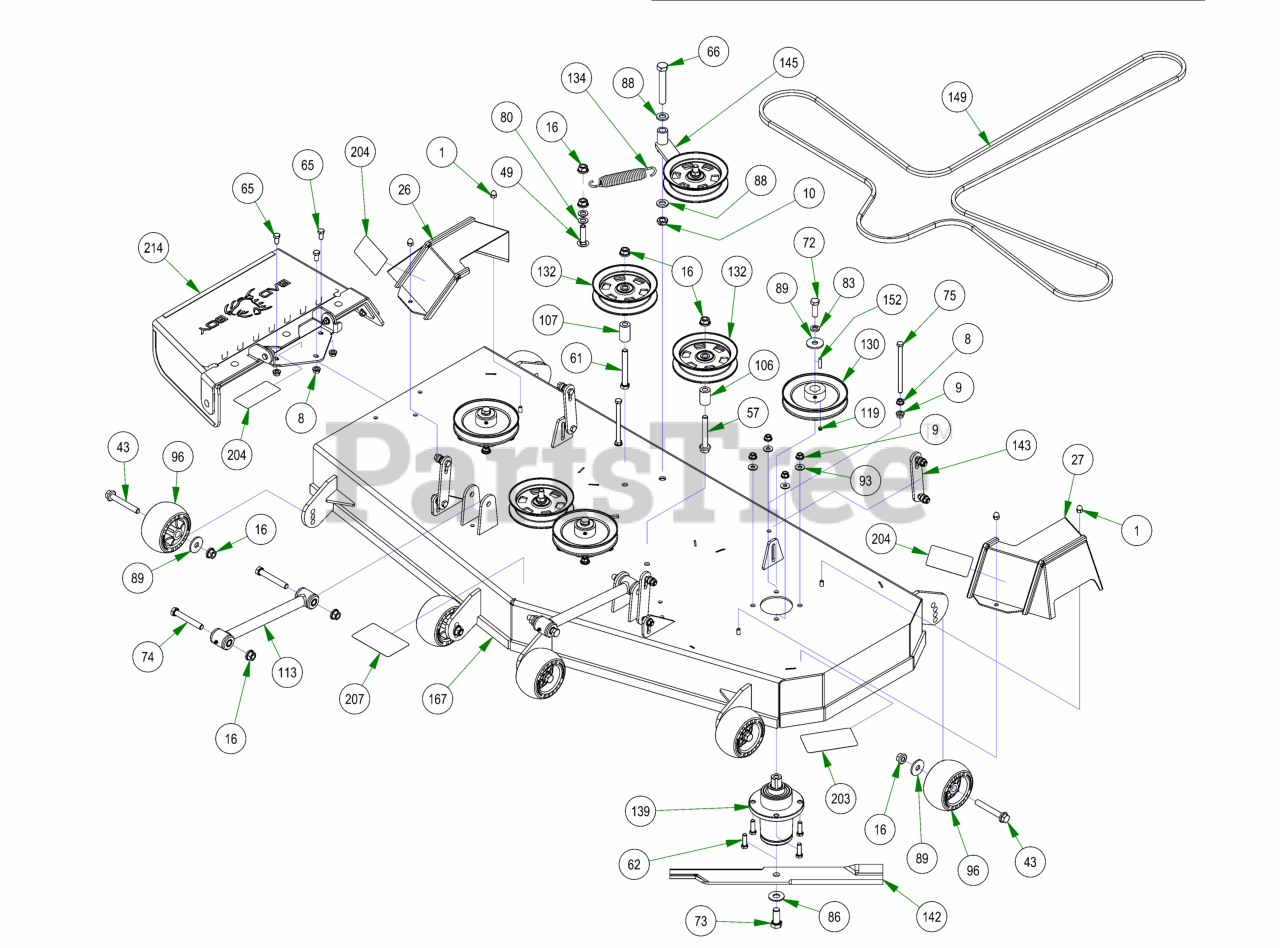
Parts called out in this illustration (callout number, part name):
1	5/16-18 ACORN NUT HIGH-CROWN ZC
8	3/8-16 HEX SERRATED FLANGE NUT HARD/ZINC
9	3/8-16 NYLON INSERT FLANGE LOCKNUT (GR.F) ZINC
10	5/8-11 NYLON INSERT JAM LOCKNUT ZINC
16	1/2-13 NYLON INSERT FLANGE LOCKNUT ZINC
26	2021 Maverick 54”/60” RH Pulley Cover
27	2021 Maverick 54”/60” LH Pulley Cover
43	1/2-13 X 90MM HEX FLANGE BOLT W/SHOULDER (GR.8) ZINC
49	1/2-13 X 2 CARRIAGE BOLT ZINC
57	1/2-13 X 3-1/2 HEX FLANGE BOLT (GR.8) ZINC
61	1/2-13 X 4 HEX CAP SCREW (GR.8) ZINC YELLOW
62	3/8-16 X 1-1/4 HEX CAP SCREW (GR.5) ZINC
65	3/8-16 X 3/4 HEX CAP SCREW (GR.5) ZINC
66	5/8-11 X 4 HEX CAP SCREW (GR.8) ZINC YELLOW
72	1/2-20 X 1-1/2 HEX CAP SCREW (GR.5) ZINC
73	5/8-18 X 1-1/2 HEX CAP SCREW (GR.8) ZINC YELLOW
74	1/2-13 X 3-1/2 HEX CAP SCREW (GR.5) ZINC
75	3/8-16 X 5-1/2 HEX CAP SCREW (GR.5) ZINC
80	.517 SQ WDTH ID X .937 OD X .060 THICK F/W PHOS/OIL
83	1/2 SPLIT LOCKWASHER (GR.8) ZINC/YELLOW
86	5/8 USS FLAT WASHER (1-3/4" OD) GR.8 ZINC YELLOW
88	.635 ID X 1.120 OD X .140 THICK FLAT WASHER NYLON
89	1/2 BELLEVILLE WASHER (1-5/8 OD X .140 THK) ZINC
93	5/16 USS FLAT WASHER (7/8 OD) ZINC
96	Deck Wheel
106	.502 ID X .750 OD X 1.500 Long Spacer
107	1 3/4" Pulley Spacer
113	Hybrid Turnbuckle/Deck Locator
119	5/16-24 X 1/4 SOCKET SET SCREW (CUP PT) PLAIN
130	6 1/4" Drive Pulley
132	5-3/4 Idler Pulley
134	Deck Idler Spring
139	Spindle Assembly
142	60" High Lift Fusion Blade
143	Deck Hanger Assembly
145	2017 MZ/ZT Deck Idler Assembly
152	1/4 X 1 SQ MACHINERY KEY 1018 STL PLN
167	2017 60" ZT Deck Welded Assembly
203	2018 60" Deck Decal
204	Danger Decal-Spindle/Discharge
207	Deck Belt Route Decal
214	Discharge Chute Assembly
